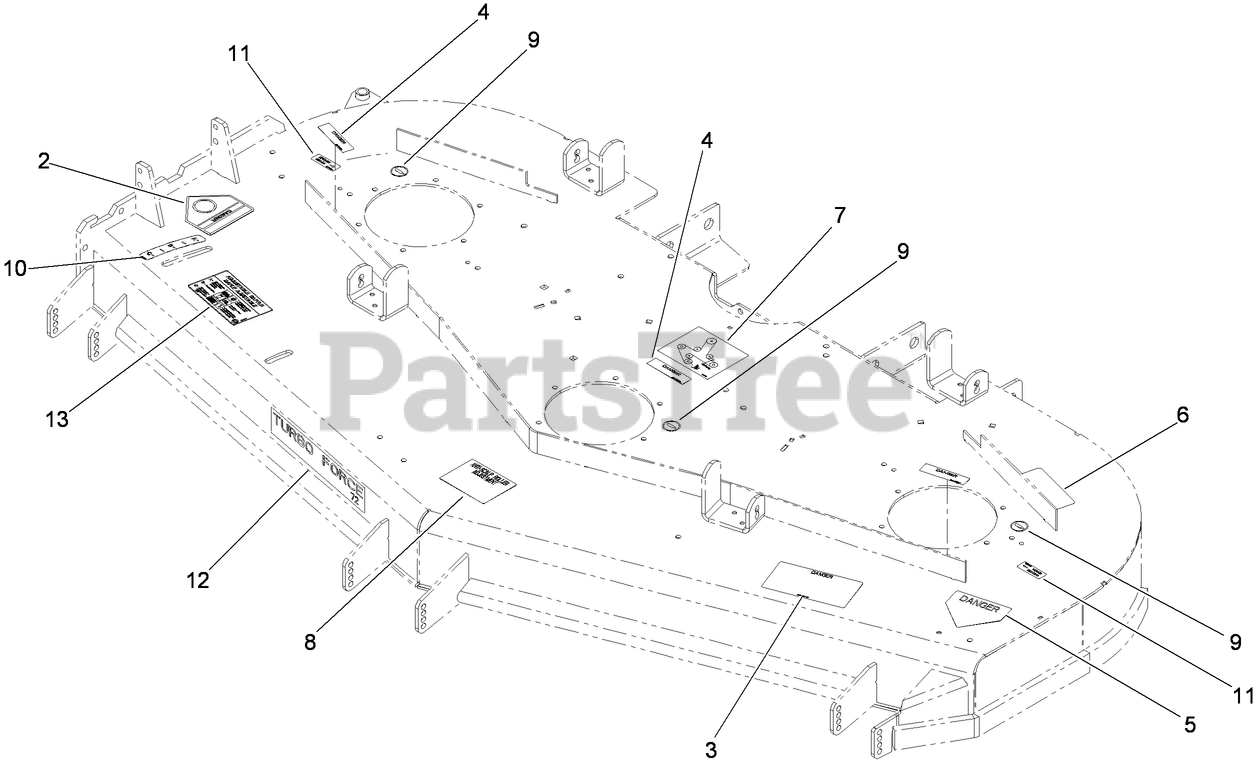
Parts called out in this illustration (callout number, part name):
2	DECAL-DANGER
3	DECAL-DANGER, THROWN OBJECT
4	DECAL-COVER, MISSING
5	DECAL-DANGER
6	DECAL-TORQUE
7	DECAL-ROUTING, BELT
8	DECAL-SCALP, ANTI
9	DECAL-GREASE
10	DECAL-SETTING, BAFFLE
11	Decal-Grease
13	DECAL-ADJUSTMENT, BAFFLE
